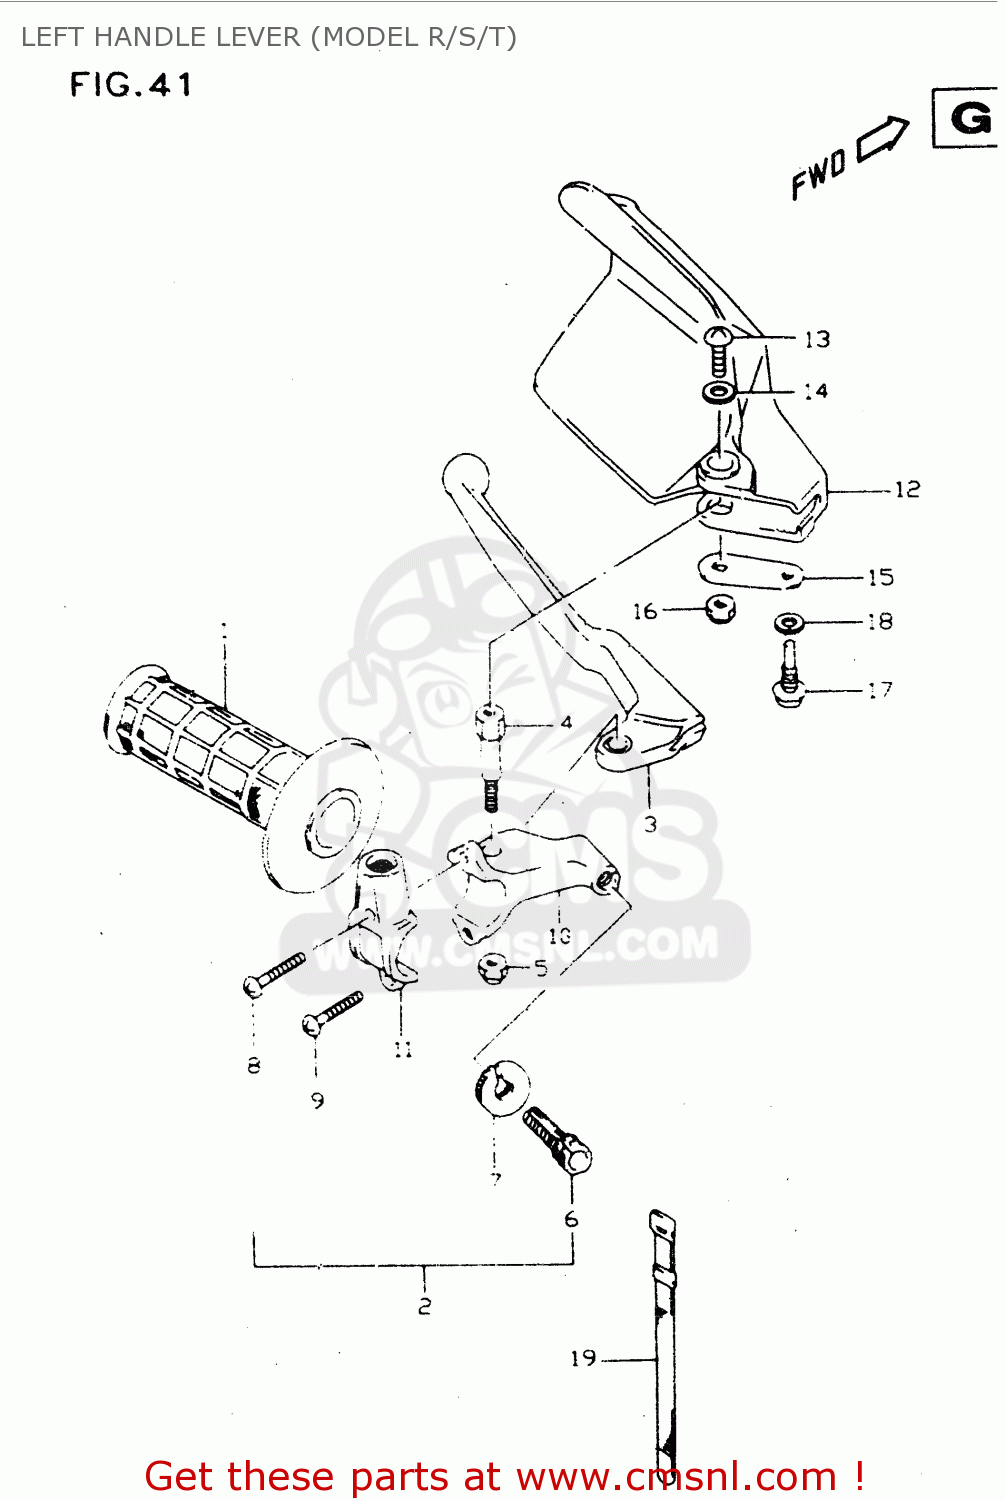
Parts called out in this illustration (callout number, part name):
1	GRIP,L
2	LEVER ASSY,CLUTCH
3	LEVER,CLUTCH
4	BOLT,LEVER SET
5	NUT 6MM
6	ADJUSTER,CABLE
7	NUT,LOCK
8	SCREW
9	SCREW(5X14)
10	HOLDER,CLUTCH LEVER
11	BRACKET,HOLDER
12	COVER,KNUCKLE,L
13	SCREW
14	WASHER (5.5X16X1.2)
15	PLATE,KNUCKLE COVER,L LWR
16	NUT 6MM
17	SCREW(6X19)
18	LOCK WASHER
19	CLAMP(L:120)
